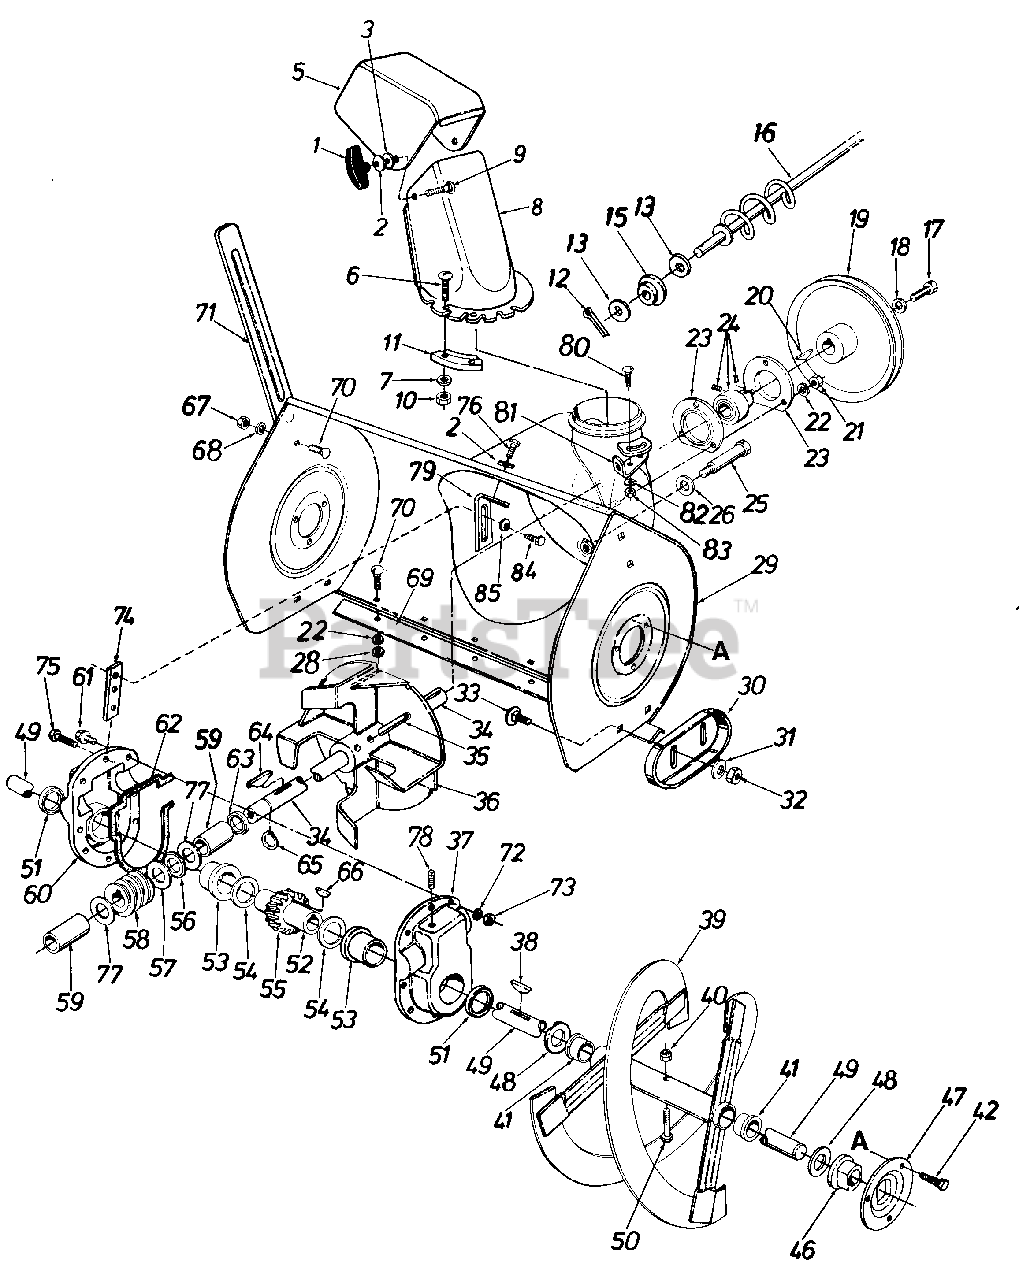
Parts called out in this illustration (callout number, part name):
1	Hand Knob Ass'y.
2	Bell-Wash. .345 I.D. x .88 O.D. x .060
3	Fl. Wash. .312 I.D. x 1.125 O.D. x .125
5	Top Chute
6	Truss Mach. Scr. 1/4-20 x .75"
7	Fl-Wash. 1/4" I.D.
8	Chute
9	Carr. Bolt 5/16-18 x 1.00" Lg.
10	Hex Cent. L-Nut 1/2-20 Thd.
11	Chute Flange Keeper
12	Cotter Pin
13	Fl-Wash. .385" I.D. x .62"
15	Bushing
16	Chute Crank Ass'y.
17	Hex L-Scr. 5/16-18 x .88" Lg.
18	Bell-Wash. .345 I.D. x .88
19	V-Pulley .875 I.D. x 10.12
20	#9 Hi-Pro Key 3/16 x 3/4" Dia.
21	Hex Nut 5/16-18 Thd.
22	L-Wash. 5/16" I.D.
23	Bearing Hsg. Self Aligning Brg.
24	Self Aligning Brg. .875 I.D.
25	Stud 3/8-16 x 2.75" Lg.
26	Bell-Wash. .400 I.D. x .88 O.D. x .060
28	Hex Nut 5/16-18 Thd.
29	Blower Hsg. Ass'y.
30	Slide Shoe
31	Bell-Wash. .400 I.D. x .88 O.D. x .060
32	Hex Jam Nut 3/8-16 Thd.
33	Carr. Bolt 3/8-16 x .62" Lg.
34	Blower Axle
35	Spring Pin Spiral 5/16" Dia. x 1.75" Lg.
38	#91 Woodruff Key 1/4" x 3/4" Dia.
39	Spiral Ass'y. L.H.
40	Hex Ins. L-Nut 5/16-18 Thd.
41	Plastic Bushing
42	Hex Wash. Hd. Tap Scr. 5/16-24 x .62" Lg.
46	Flange Brg. w/Flats 1.0" I.D.
47	Bearing Hsg. Spiral Hsg.
48	Fl-Wash. 1.06 I.D. x 1.75" O.D. x .100
49	Spiral Axle
50	Hex Bolt 5/16-18 x 1.75" Lg.
51	Oil Seal 1.50" I.D.
52	Worm Gear Shaft
53	Flange Brg. 1.503 I.D.
54	Fl-Wash. 1.5 I.D. x 2.0 O.D.
55	Double Threaded Worm Gear
56	Thrust Brg. .88 I.D. x 1.44 O.D. x .078
57	Fl-Wash. .88 I.D. x 1.40 O.D.
58	Double Threaded Worm L.H.
59	Sleeve Brg. .875 I.D.
60	Complete Gear Hsg. Half R.H.
61	Hex Bolt 5/16-18 x 1.0" Lg.
62	Gasket
63	Oil Seal .875" I.D.
64	#9 Hi-Pro Key 3/16 x 3/4" Dia.
65	Snap Ring .875" Dia.
66	#91 Woodruff Key 1/4 x 3/4" Dia.
67	Hex Nut 5/16-18 Thd.
68	L-Wash. 5/16" I.D.
70	Carr. Bolt 5/16-18 x .62" Lg.
72	Wave Wash. 5/16" I.D.
73	Hex Ins. L-Nut 5/16-18 Thd.
74	Gear Hsg. Support Plate
75	Hex Bolt 5/16-18 x 1.25
76	Hex Wash. Hd. Self-Tap Scr. 5/16-18 x .75" Lg.
77	Fl-Wash. .88 I.D. x 1.40 O.D.
78	Filler Plug
80	Carr. Bolt 5/16-18 x .75" Lg.
82	Bell-Wash. .345 I.D. x .88"
83	Hex Nut 5/16-18 Thd.
84	Hex Bolt 1/4-28 x .75" Lg.
85	Bell-Wash. .28" I.D. x .75" O.D.
05139A-0637	BLADE-GUIDE (DRIFT - POWDER BLACK (0637)
05139A-0638	BLADE-GUIDE (DRIFT - MTD/TROY-BILT RED (0638)
05139A-0662	BLADE-GUIDE (DRIFT - OYSTER GRAY (0662)
05139A-0665	BLADE-GUIDE (DRIFT - YARDMAN GREEN (0665)
05139A-0674	BLADE-GUIDE (DRIFT - YARDMAN YELLOW (0674)
05139A-0716	BLADE-GUIDE (DRIFT - CUB YELLOW-99 (0716)
